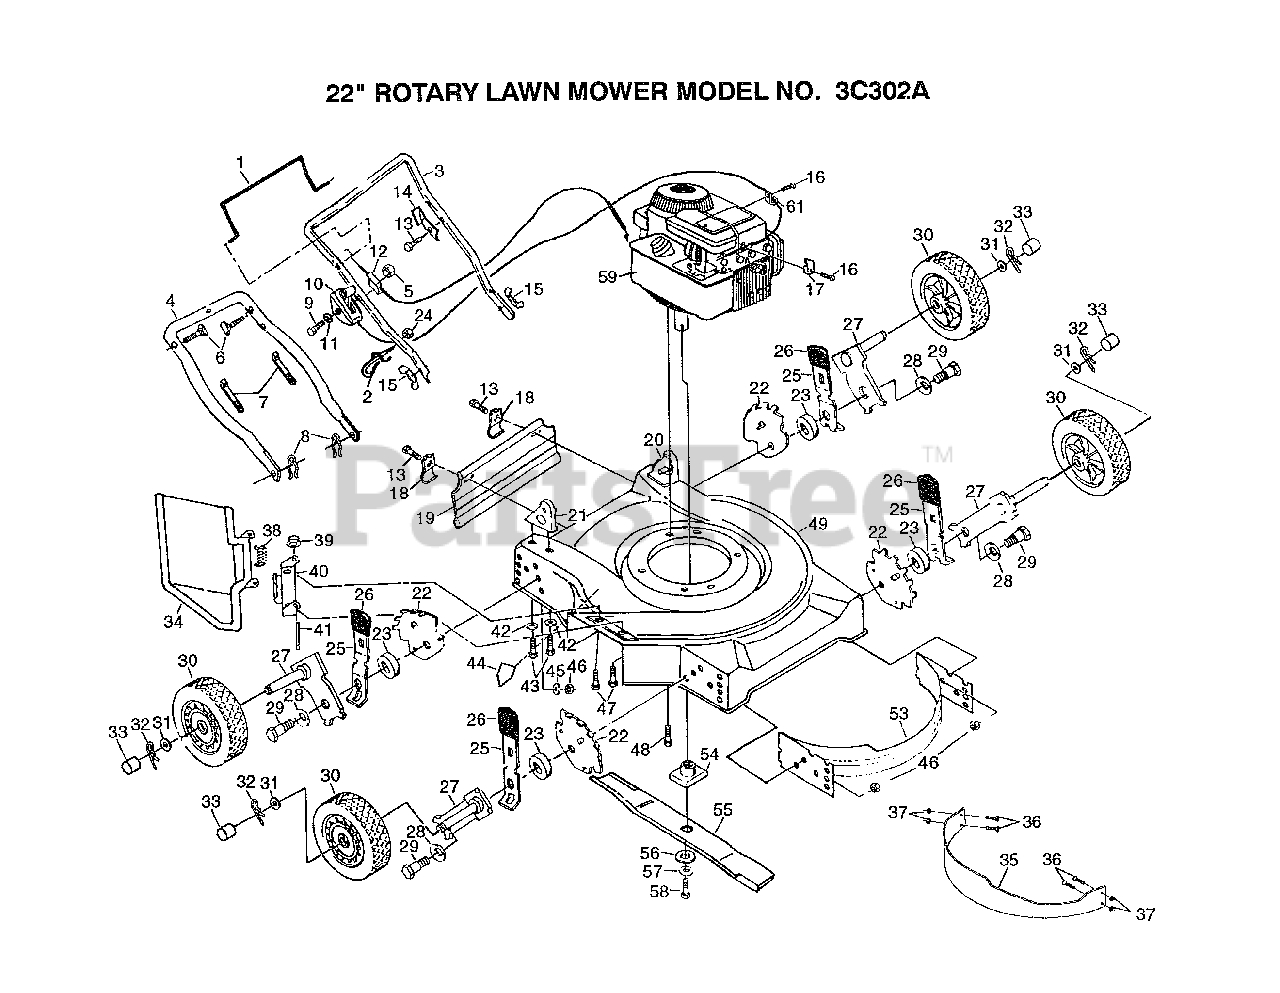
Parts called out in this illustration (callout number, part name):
1	CONTROL BAR PM
2	ROPE GUIDE
6	BOLT.HANDLE.LM
8	HAIRPIN COTTER
10	CONTROL THROTTLE
11	WASHER PM
12	"CABLE,ENG ZONE CO"
13	TAPPING SCREW
14	"BRKT,UPSTOP"
15	"NUT,WING PM"
16	SCREW PM
17	CABLE CLAMP
18	"BRKT,DEFL PM"
24	NUT
25	SPRING SELECTOR
26	KNOB PM
27	AXLE ARM
28	"WASHER, BELLEVIL."
30	WHEEL.ASM
31	WASHER
32	RETAINER CLIP PM
33	HUB CAP-PLASTIC
35	BAFFLE.MULCH.22SD
37	LOCKNUT
38	"SPRING,TORSION"
39	PUSH ON SPEED NUT
40	"BRKT,HSG"
41	"ROD,HINGE "
42	STEEL WASHER
43	SCREW
44	DECAL HYT
46	LOCKNUT PM
47	SCREW
48	SCREW
49	HOUSING KIT
53	BAFFLE.FRT/REAR
54	BLADE ADAPTOR
56	"WASHER,HARDEN"
57	LOCKWASHER
58	SCREW
61	GUIDE CLIP PM
